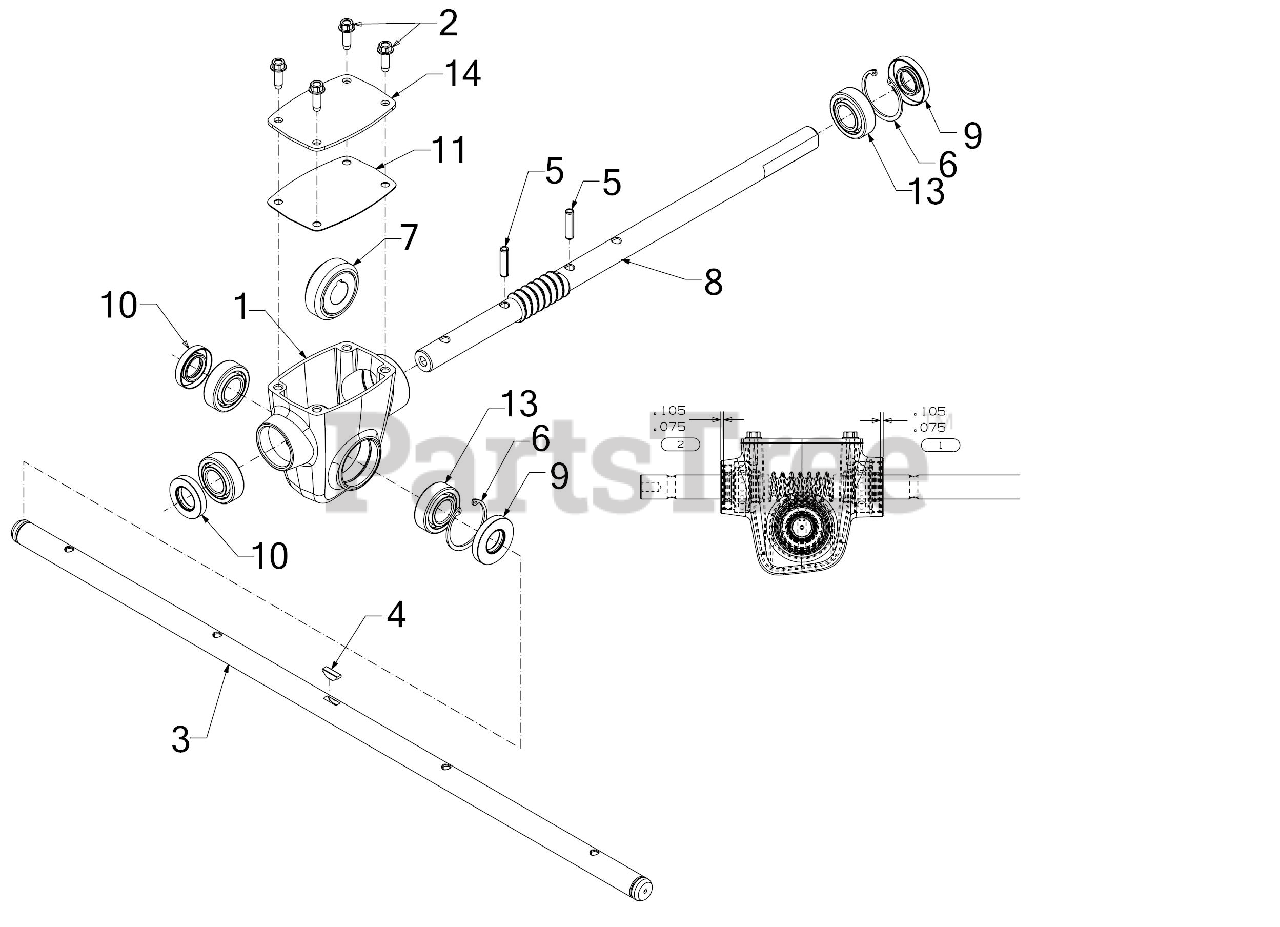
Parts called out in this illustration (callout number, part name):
1	AUGER GEARBOX HOUSING
2	SCREW 1/4-20 x .750
3	28" AUGER AXLE
4	KEY 3/16 x 5/8 H
7	WORM GEAR 20T
11	GEARBOX COVER GASKET
13	BALL BEARING
14	GEARBOX COVER
